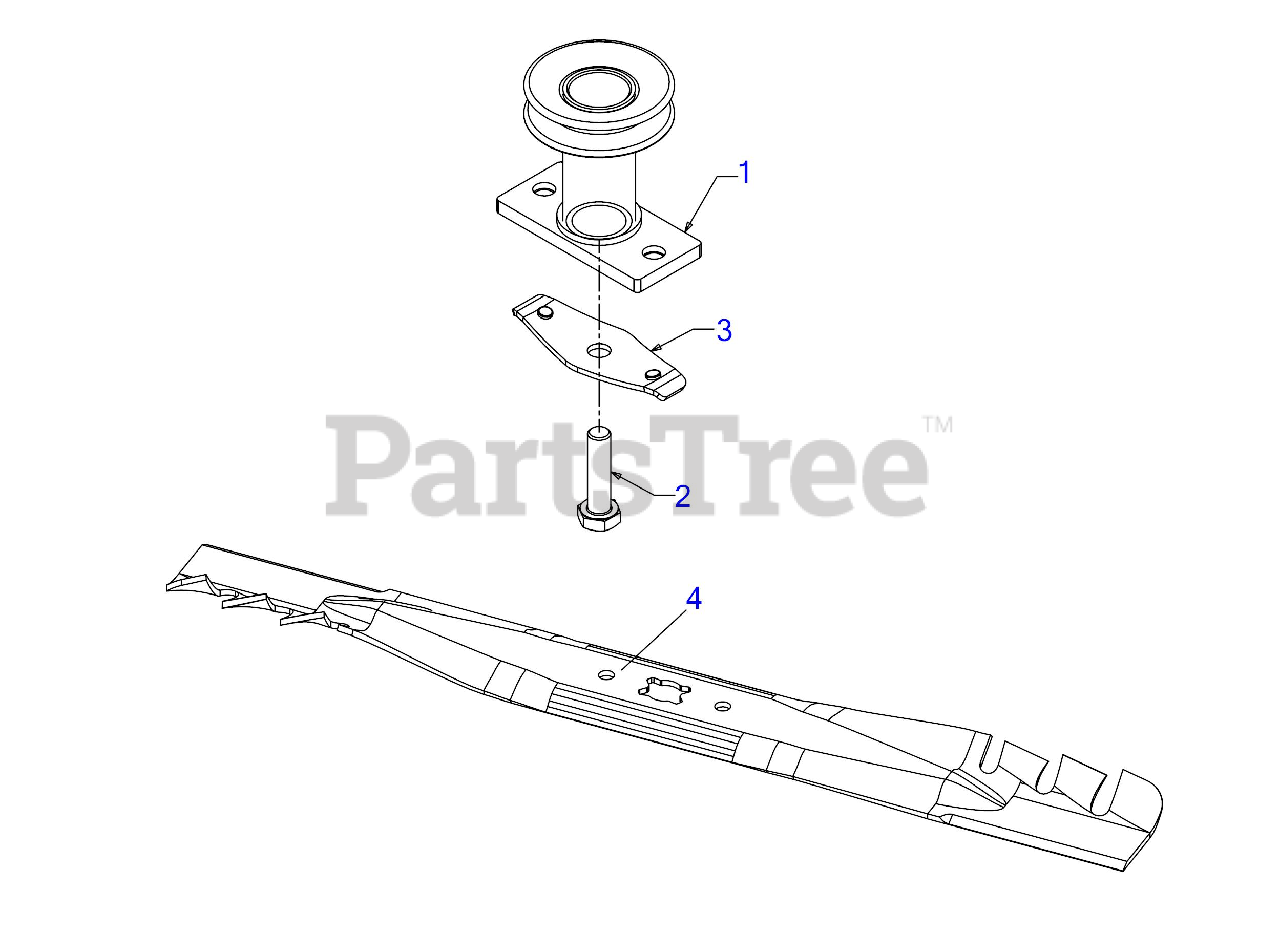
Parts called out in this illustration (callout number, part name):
1	BLADE ADAPTER
2	SCREW 3/8-24 x 1.50 GR8
3	BLADE BELL SUPPORT
4	21" BLADE (XTREME)
